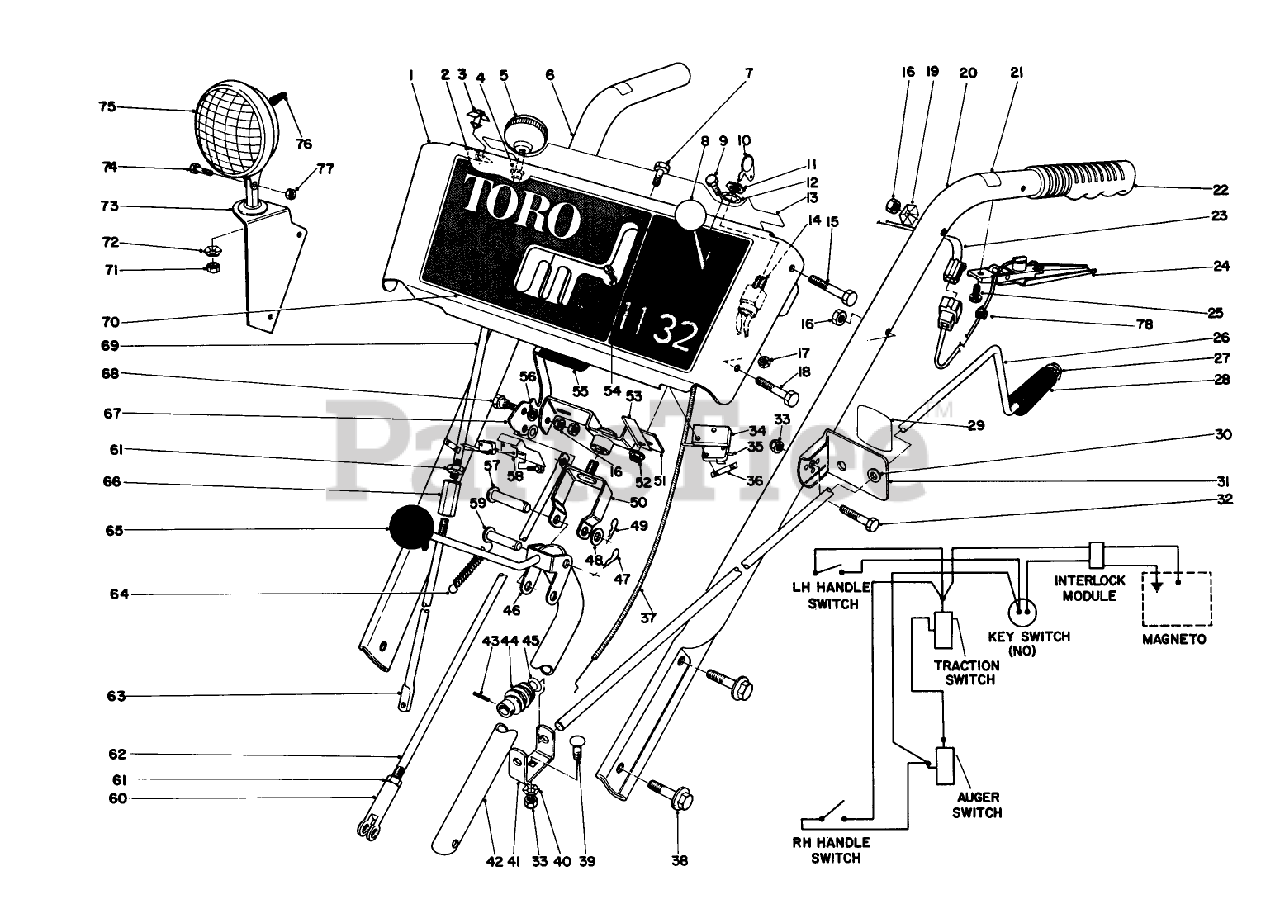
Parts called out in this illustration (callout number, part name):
4	NYLINER #6LI-FF TYPE 7
5	KNOB-LEVER
7	SCREW-HH
12	WASHER-LOCK
15	SCREW-HH
16	NUT-LOCK, CONE
17	NUT-LOCK, NI
18	SCREW-HH
25	SCREW
27	NUT-PUSH
28	GRIP-CONTROL, CHUTE
32	SCREW-HH
33	NUT-LOCK, NI
35	SWITCH-MICRO
36	NUT-SPEED
38	SCREW-HHF
40	Pyramidal Washer
41	Bracket-Worm
42	Rod-Traction Shift
43	Roll Pin
44	Worm Gear-Chute
45	WASHER-SPRING
46	SHIFT ROD WA
48	WASHER-FLAT
49	PIN-HAIR
52	NUT-LOCK, HHF
54	SCREW-SPH
56	WASHER-PLAIN
57	PIN-CLEVIS
58	SWITCH BRKT
59	PIN-CLEVIS
60	CLEVIS
61	NUT-HJ
63	LOWER WHL CLUTCH ROD
66	WHL ROD COUPLING
68	SCREW-SHOULDER
71	NUT-HEX
72	LOCKWASHER-PYRAMID
74	SCREW-HH
76	BOOT-SWITCH
77	NUT-HEX, SIDE DEFORM
78	WIRE MOUNT
